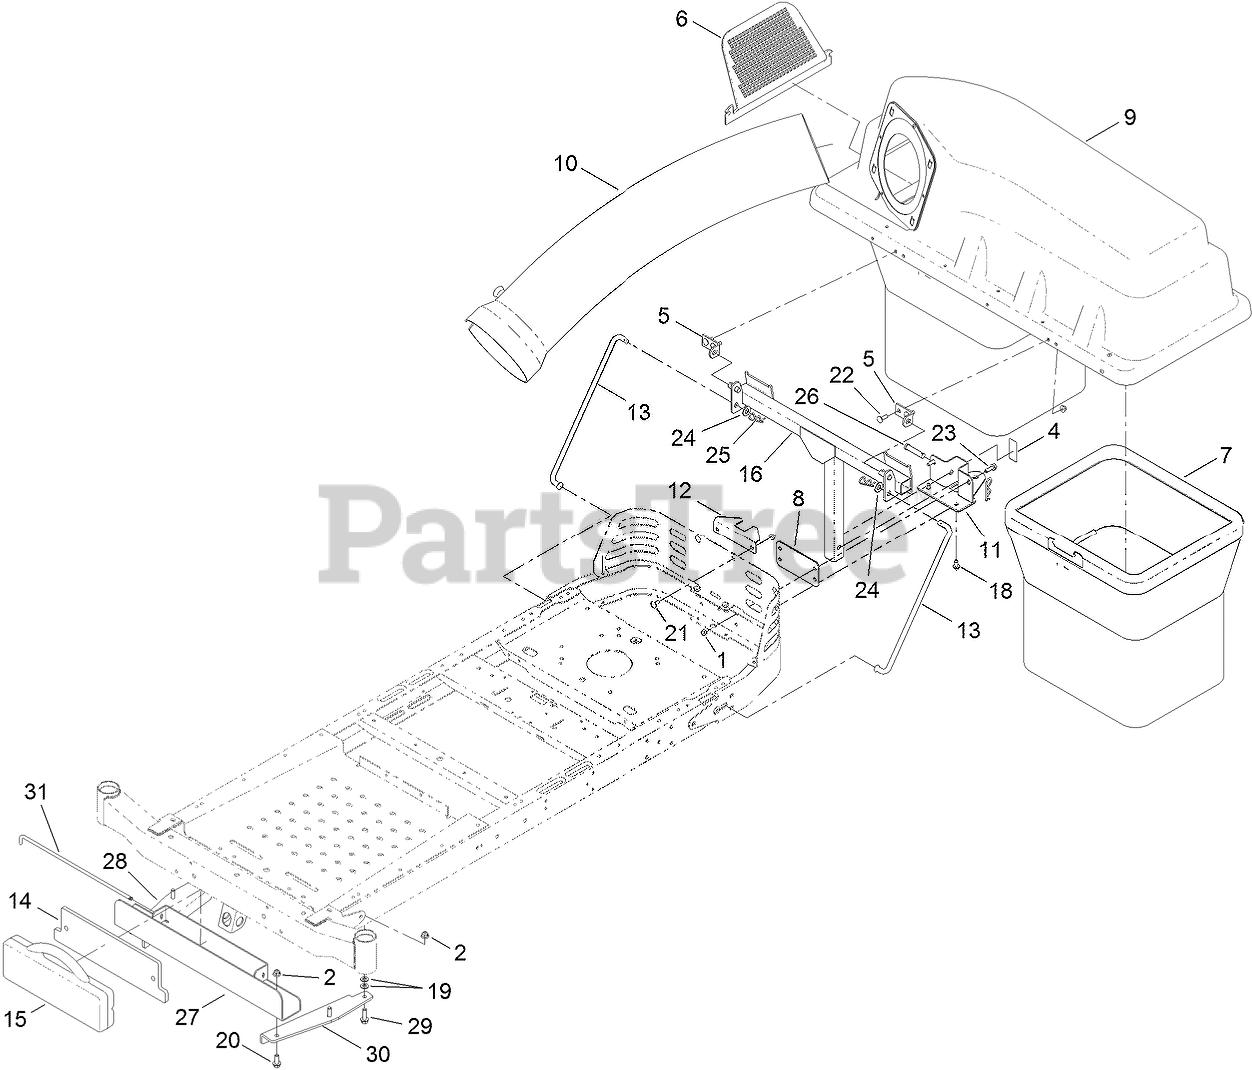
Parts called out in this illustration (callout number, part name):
1	NUT-HF, NI
2	NUT-HF, NI
5	BRACKET-PIVOT, HOPPER
6	SCREEN-BAGGER
7	BAG ASM
9	BAGGER TOP ASM
10	TUBE-BAGGER
11	SUPPORT-BAGGER
12	BRACKET-STABILIZER
13	ROD-SUPPORT
15	WEIGHT-35 POUND
16	FRAME-PIVOT
18	SCREW-HWHTF
19	WASHER-FLAT
20	SCREW-HHF
21	BOLT-CARR
22	BOLT-CARR
23	SCREW-HHF
24	WASHER-FLAT
25	PIN-HAIR
26	PIN-CLEVIS
27	CHANNEL-WEIGHT, BAGGER
28	BRACKET-BAGGER WEIGHT, RH
29	SCREW-HHF
30	BRACKET-BAGGER WEIGHT, LH
31	PIN-WEIGHT
